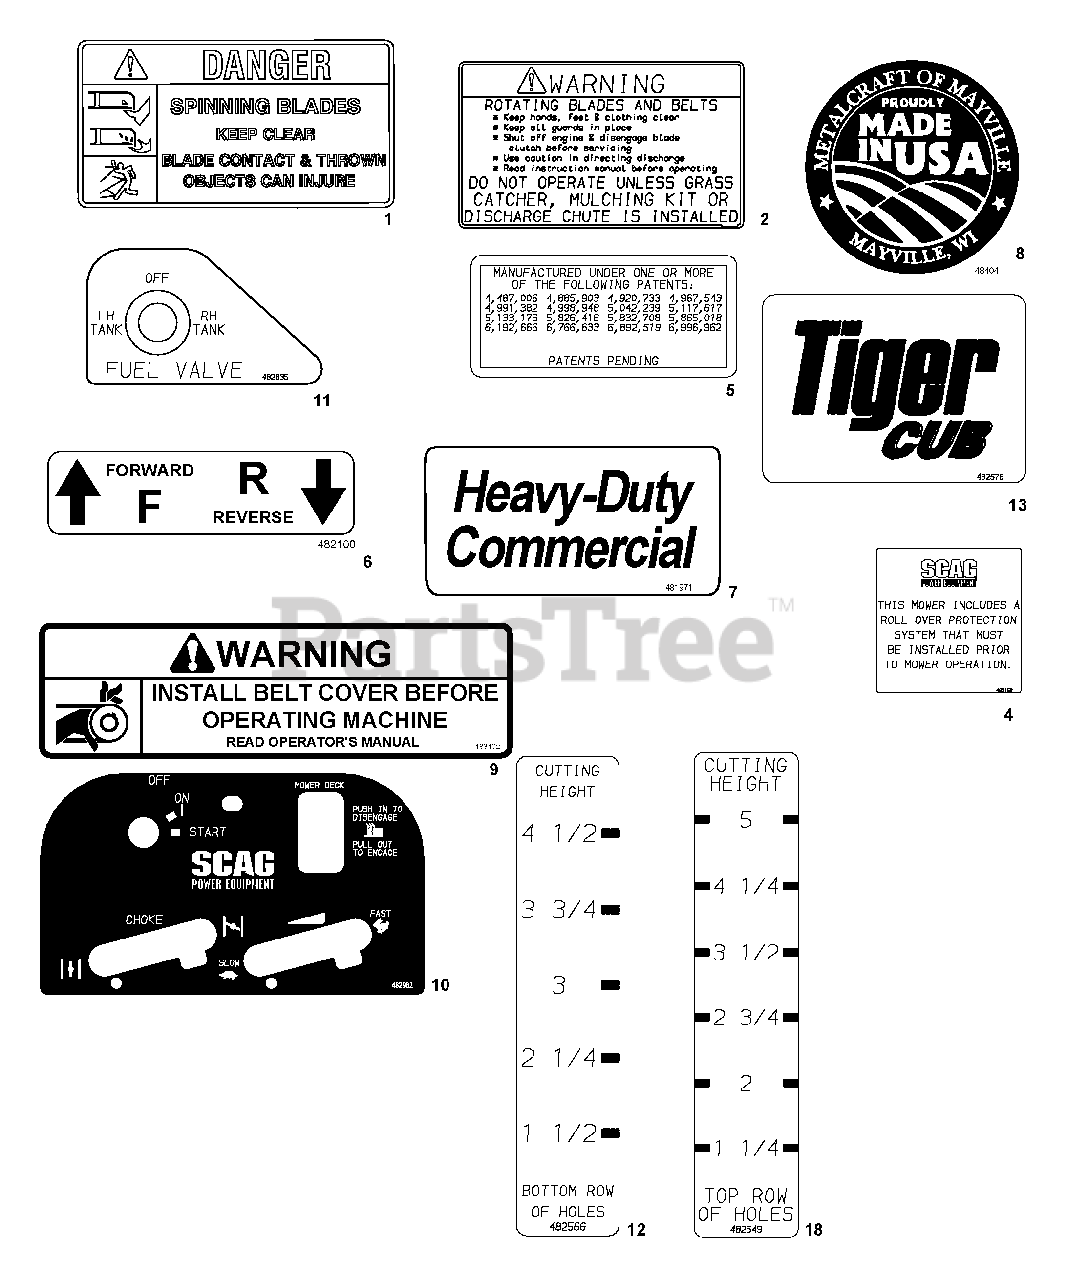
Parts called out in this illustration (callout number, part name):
1	Decal, Danger-Spinning Blades
2	Decal, Warning-Rotating Blades
4	Decal, ROPS
5	Decal, Patents
6	Decal, Traction Control
7	Decal, Heavy Duty Commercial
8	Decal, Metalcraft - Made in USA
9	Decal, Belt Cover
10	Decal, Instrument Panel
11	Decal, Fuel Valve Position
12	Decal, Cutting Height Bottom Row of Holes
13	Decal, Tiger Cub
18	Decal, Cutting Height Top Row of Holes
